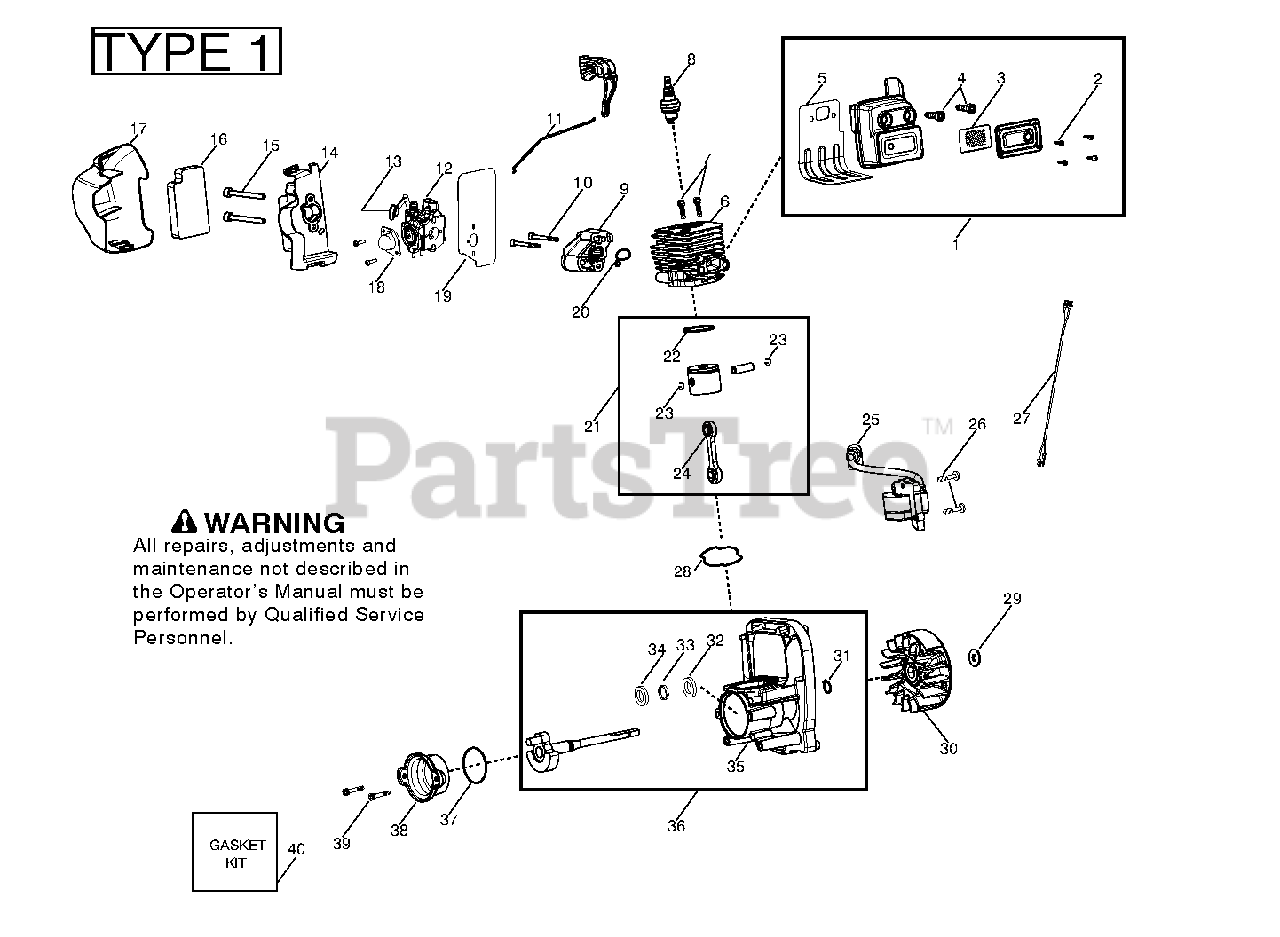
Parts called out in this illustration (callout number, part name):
1	ASSY MUFFLER
2	SCREW-6-19X5/16PLAST PA
3	KIT SPARK SCREEN
4	BOLT MUFFLER
5	KIT GASKET 25CC
6	CYLINDER CHROME 25CC
8	PLUG-SPARK (RCJ-6Y)
9	ADAPTER CARBURETOR
11	LINKAGE THROTTLE
12	KIT CARBURETOR WT-875A
13	CHOKE LEVER
13	LEVER CHOKE WT-875
14	BASE AIRBOX RED
16	AIR FILTER FOAM
17	COVER AIRBOX BLACK
18	PURGE BULB 188-16
19	KIT GASKET 25CC
20	KIT GASKET 25CC
21	KIT PISTON CONN ROD
22	RING-PISTON
23	WRIST PIN RET.
24	KIT PISTON CONN ROD FORGED
25	KIT MODULE W/0 INTERRUPT
27	HARNESS WIRE
28	KIT GASKET 25CC
29	WASHER FLAT
30	FLYWHEEL
31	RETAINING RING
32	OUTER BEARING
34	BEARING
35	ASSY CRANKCASE
36	ASSY CRANKCASE & CRANKSHAFT
37	KIT GASKET 25CC
38	ASSY REAR PLUG
40	KIT GASKET 25CC
